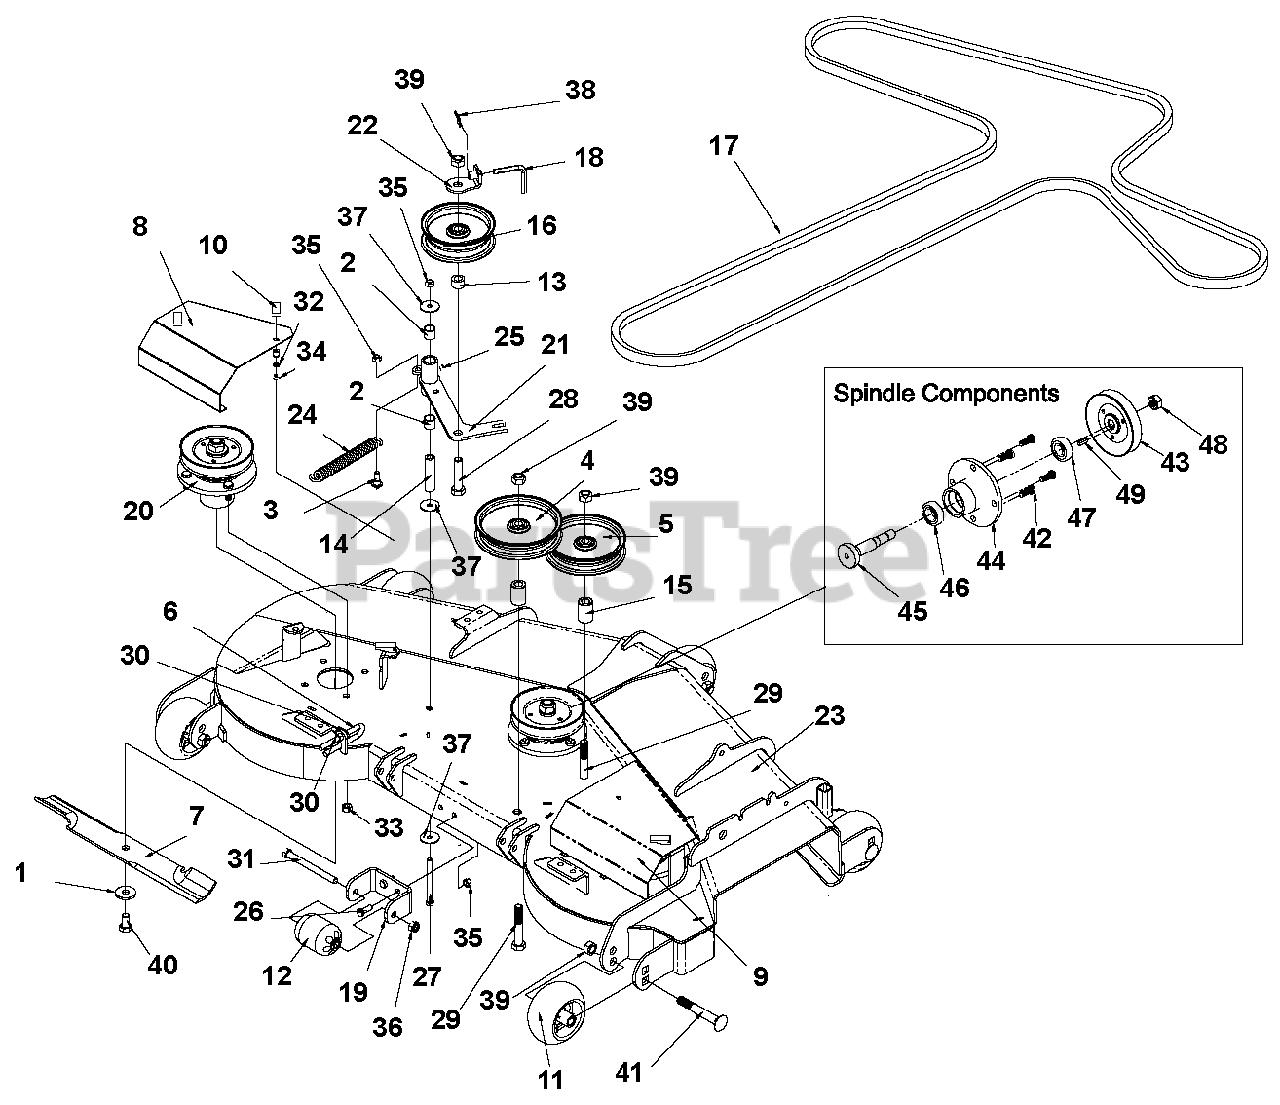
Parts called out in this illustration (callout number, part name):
1	Washer, M14 x M40 x M4.5 FLAT
2	Bearing, Sleeve .753 x .878 x .750
3	Bolt, 1/2 x 1.06 x 3/8-16 SLD 5
4	Pulley, Flat 6.00 x .635 w/Bearing
5	Pulley, Flat 5.50 x .635 w/Bearing
6	U-Bolt, Round .63 x 4.50 x 3/8-16
7	Blade, 18.000 LO-Lift - 52" Deck (400)
8	Shield, LH ZTM Belt
9	Shield, RH ZTM Belt
10	Latch, 12-24 SouthCO
11	Wheel, Gauge Ø5.00 x 2.75 SYM
12	Wheel, Gauge Ø2.56 x 3.94 SYM
13	Bushing, .688 x 1.13 x .625
14	Tube, .750 x .438 x 3.047
15	Bushing, .688 x 1.13 x 1.68
16	Pulley, Flat 5.00 x .635 w/Bearing
17	Belt, B144K Special - 52" Deck (400)
18	Belt Keeper, 90° w/Hole
19	Bracket, Anti-Scalp
20	Assembly, Spindle Ball Bearing - 52" Deck (400)
21	Weldment, Deck Belt Tensioner
22	Weldment, Belt Keeper
23	Weldment, 52Z Deck (400)
24	Spring, Extension .910 x .177 x 6.15
25	Fitting, 1/4-28 TPR 45 Grease Zerk
26	Bolt, 3/8-16 x 1.00 Hex 5
27	Bolt, 3/8-16 x 4.00 Hex 5
28	Bolt, 5/8-11 x 2.75 Hex 5
29	Bolt, 5/8-11 x 3.50 Hex 5
30	Nut, 3/8-16 STD Hex GR5
31	Bolt, M12 x 1.75 x 130 Hex 8.8
32	Washer, M6 REG Flat
33	Nut, 7/16-20 HEX GR5
34	Locknut, 12-24 Nyloc
35	Locknut, 3/8-16 Crown
36	Locknut, M12 x 1.75 Nyloc
37	Washer, .375 x 1.50 x .O63 Flat
38	Ring, Rue .625 x .072 x 1.690
39	Locknut, 5/8-11 Crown
40	Bolt, 9/16-12 x 1.00 Hex 8
41	Bolt, 5/8-11 x 4.50 CRG
42	Bolt, 7/16-20 x 1.22 SPC 5
43	Pulley, V-Belt 5.75 x .750 52" (400)
44	Spindle, Machined Ball Bearing
45	Shaft, Spindle
46	Bearing, Ball M25 x M52 x M15 6205
47	Bearing, Ball M20 x M52 x M15 6304 (402)
48	Locknut, 3/4-16 Crown
49	Key, .250 X .250 X 1.00 SQ
